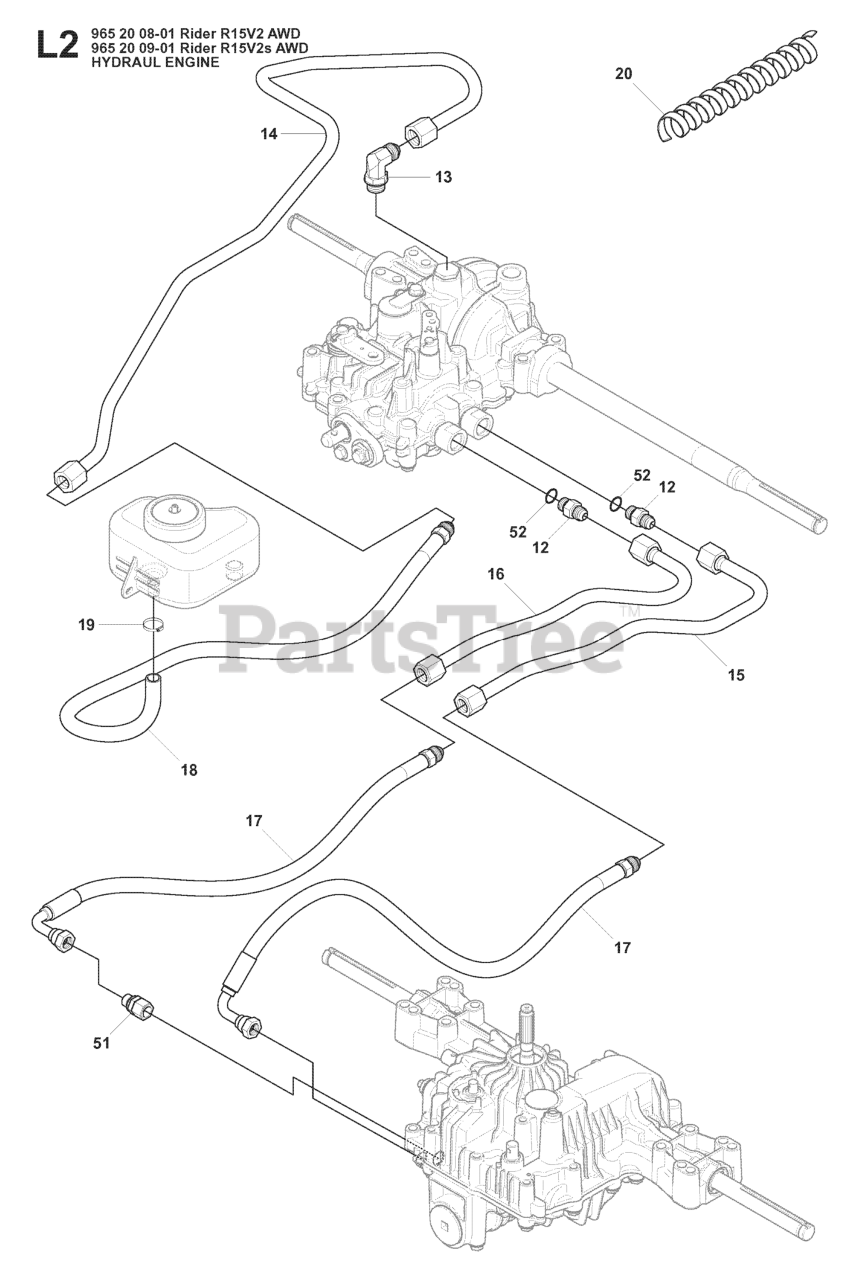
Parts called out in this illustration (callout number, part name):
12	PIPE FITTING
14	HYDRAULIC PIPE
15	HYDRAULIC PIPE
16	HYDRAULIC PIPE
17	HYDRAULIC HOSE
18	RP HOSE
19	CLAMP
20	HOSE GUARD D=43 L=400
